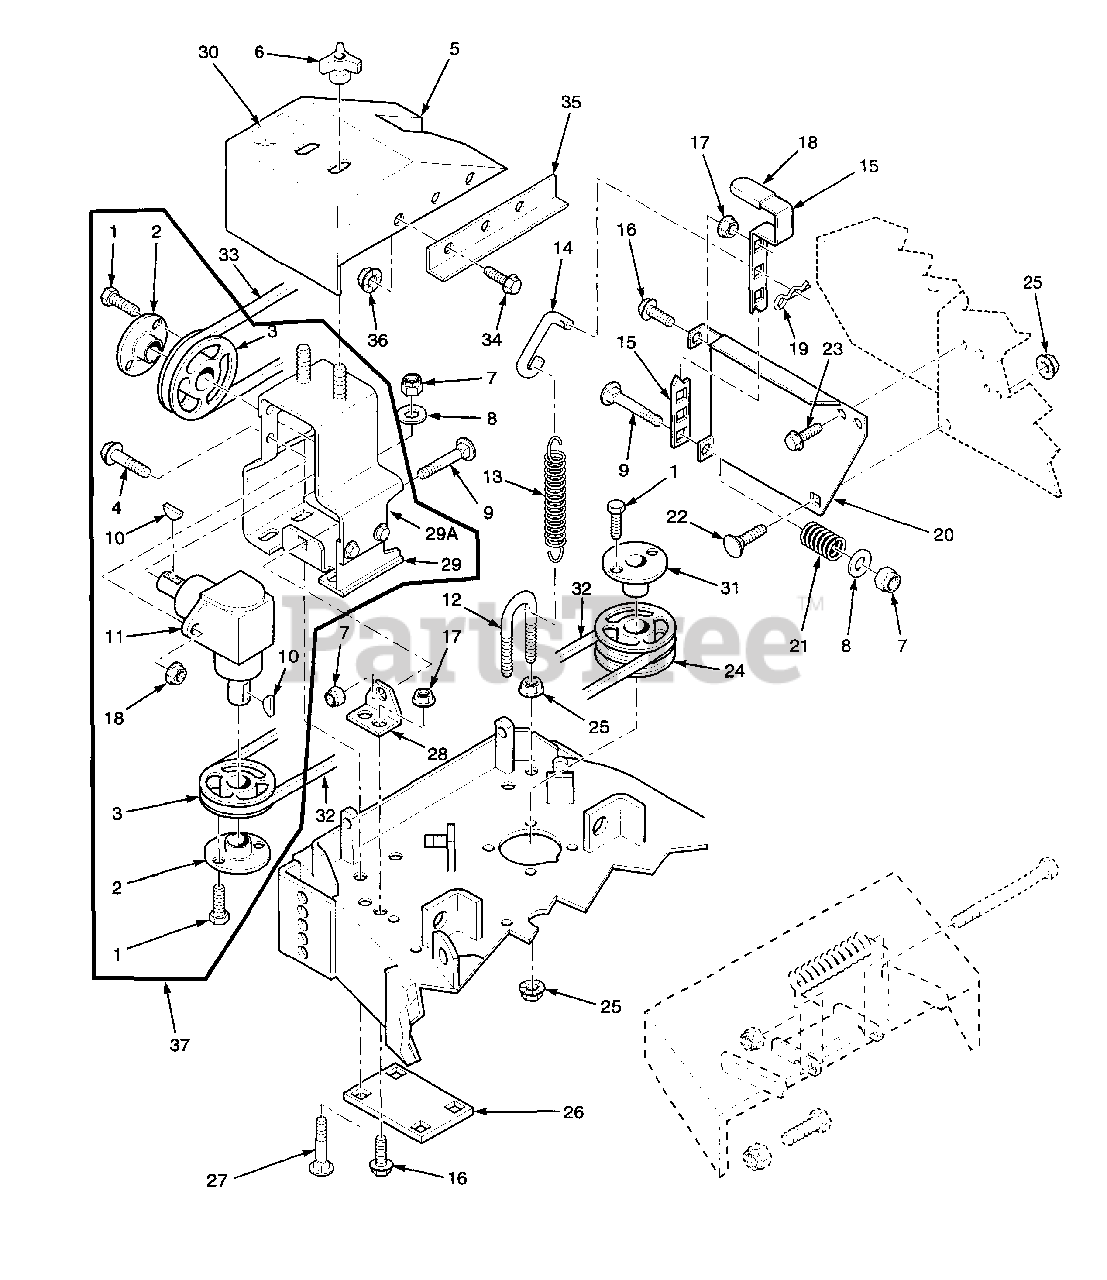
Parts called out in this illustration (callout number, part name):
1	Bolt, Hex Head 1/4-20 x .75
2	Tapered Hub, .875 Bore
3	Pulley, Tapered Bore 5.75 O.D.
4	Capscrew, Serr. Flange 3/8-16 x 1.25
5	Belt Cover, w/Decal
6	Wingnut, Plastic 3/8-16 x .875
7	Nut, Elastic Stop 3/8-16
8	Flat Washer, 3/8 (.375 x 2.00 x .060)
9	Carriage Bolt, 3/8-16 x 2.00
10	Key, Woodruff #9 3/16 x .75
11	Gear Box, 90 Degree Drive
12	U-Bolt, 5/16-18 x 2.19
13	Spring,Counter Balance
14	Rod, Counter Balance
15	Lever, Counter Balance
16	Capscrew, Serr. Flange 3/8-16 x .75
17	Nut, Serr. Flange 3/8-16
18	Grip, Shift Lever
19	Hair Pin, .094 x 1.62
20	Mounting Bracket, Counter Balance
21	Spring, Compression
22	Carriage Bolt, 5/16-18 x 1.00
23	Capscrew, 5/16-18 x .75
24	Pulley, Double Groove 5.75 O.D.
25	Nut, Serr. Flange 5/16-18
26	Reinforcement Plate, Gear Box
27	Carriage Bolt, 3/8-16 x 1.25
28	Anchor Bracket, Tension Bolt
29	Support Weldment, Gearbox-upper
29A	Support Weldment, Gearbox-lower
30	Decal, Warning
31	Tapered Hub, 1.00 Bore
32	Belt, Gearbox Drive
33	Belt, Blower Drive
34	Capscrew, 1/4-20 x .50 Serr. Flange
35	Skirt, Belt Cover
36	Nut, 1/4-20 Serr. Flange
37	Gearbox Assembly
